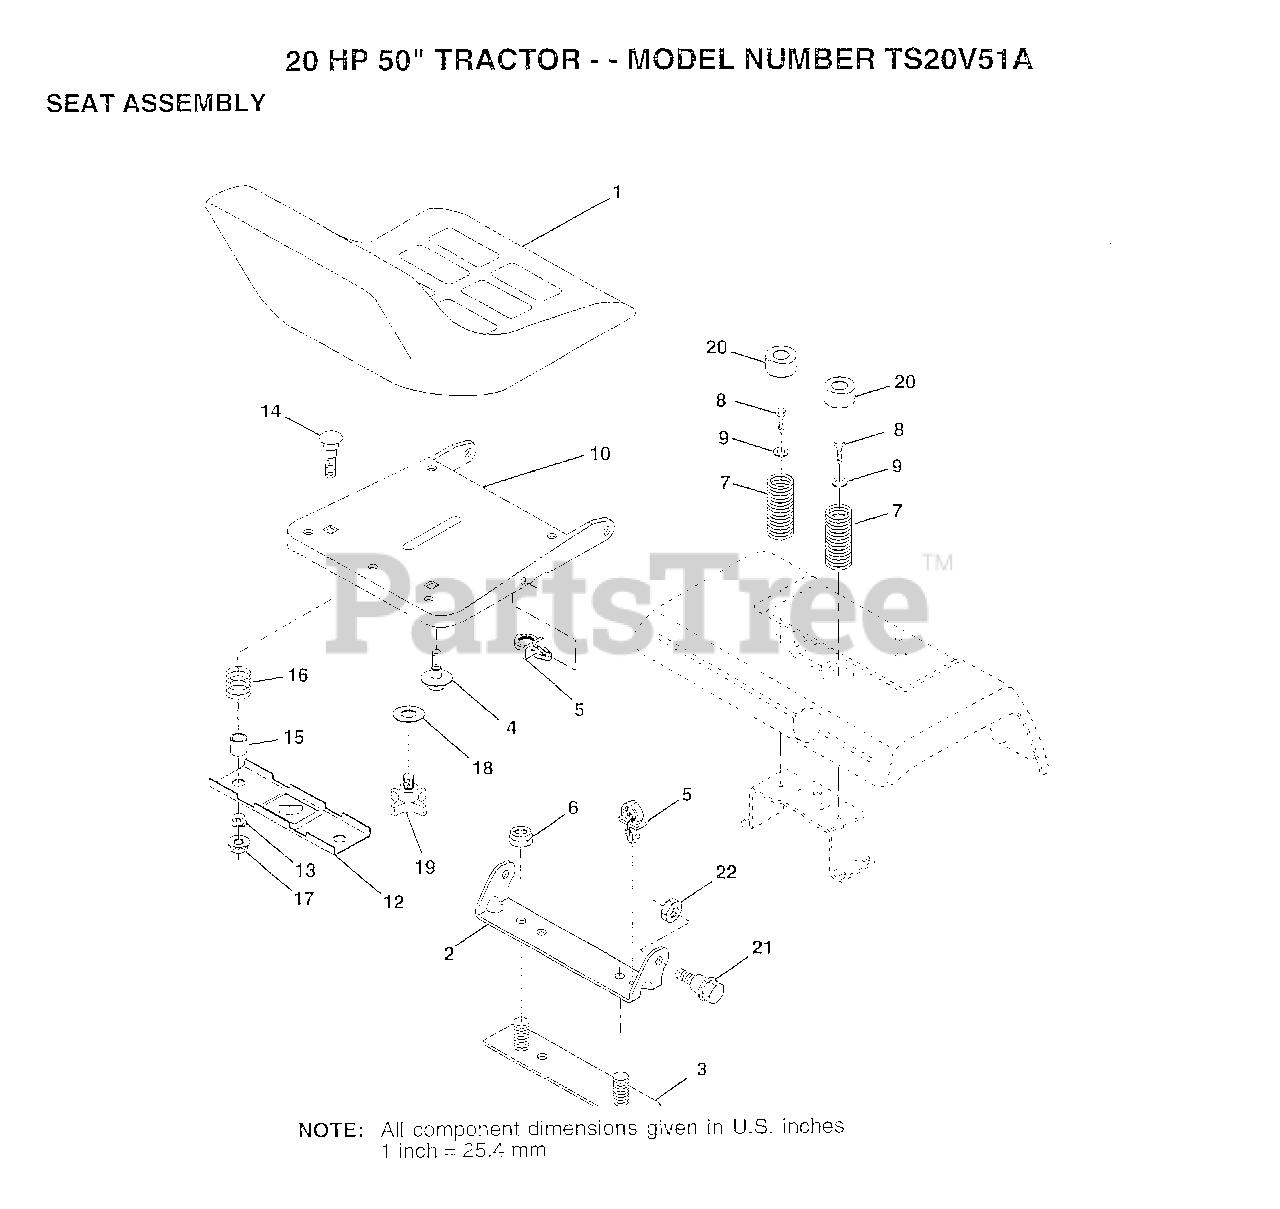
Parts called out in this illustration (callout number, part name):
2	BRACKET PVT SEAT
3	STRAP ASM FENDER
4	"BOLT,SHOULDER"
5	CLIP PUSH - IN
6	NUT
7	SPRING COMPRESSIO
8	SCREW LT
9	WASHER
12	BRKT SWITCH
13	BUSHING
15	SPACER SPLIT
16	SPRING COMPRESSED
18	WASHER
19	"KNOB 1/2"" YT"
20	CAP SPRING
21	BOLT.SHLD.5/16-18
